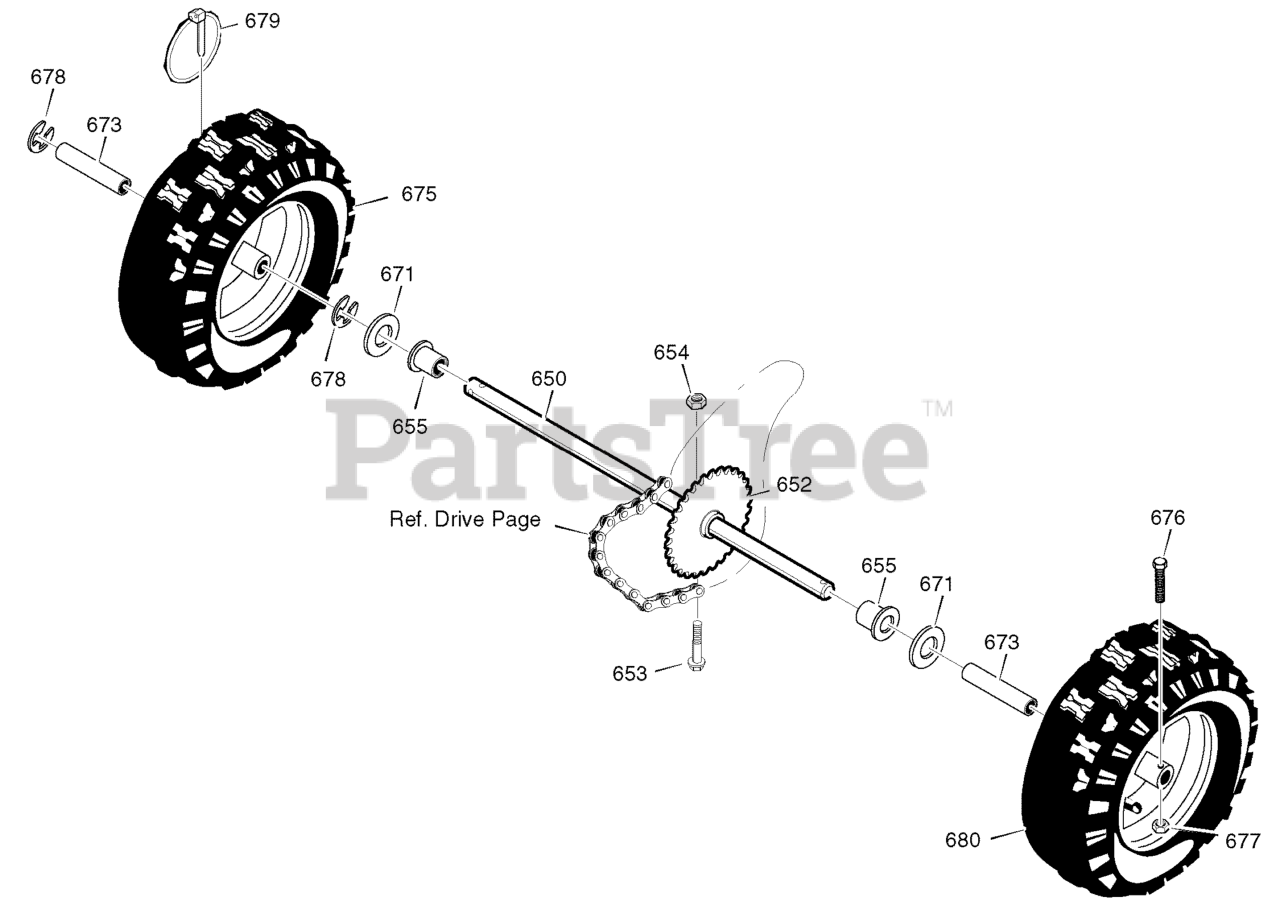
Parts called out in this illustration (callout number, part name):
650	SHAFT, AXLE
652	SPRKT & HUB
653	SCREW, 1/4-20 x 1.75
654	NUT, 1/4-20 HEX NYLOCK
655	BEARING, AXLE
671	WASHER, FLAT
673	BUSHING, WHEEL
675	TIRE & RIM, RIGHT
676	BOLT 1/4-20X1.75 HH
677	NUT, 1/4-20 HEX NYLOCK
678	RING, RET
679	PIN, KLIK .25 X 1.38 DIA
680	TIRE & RIM, LEFT
